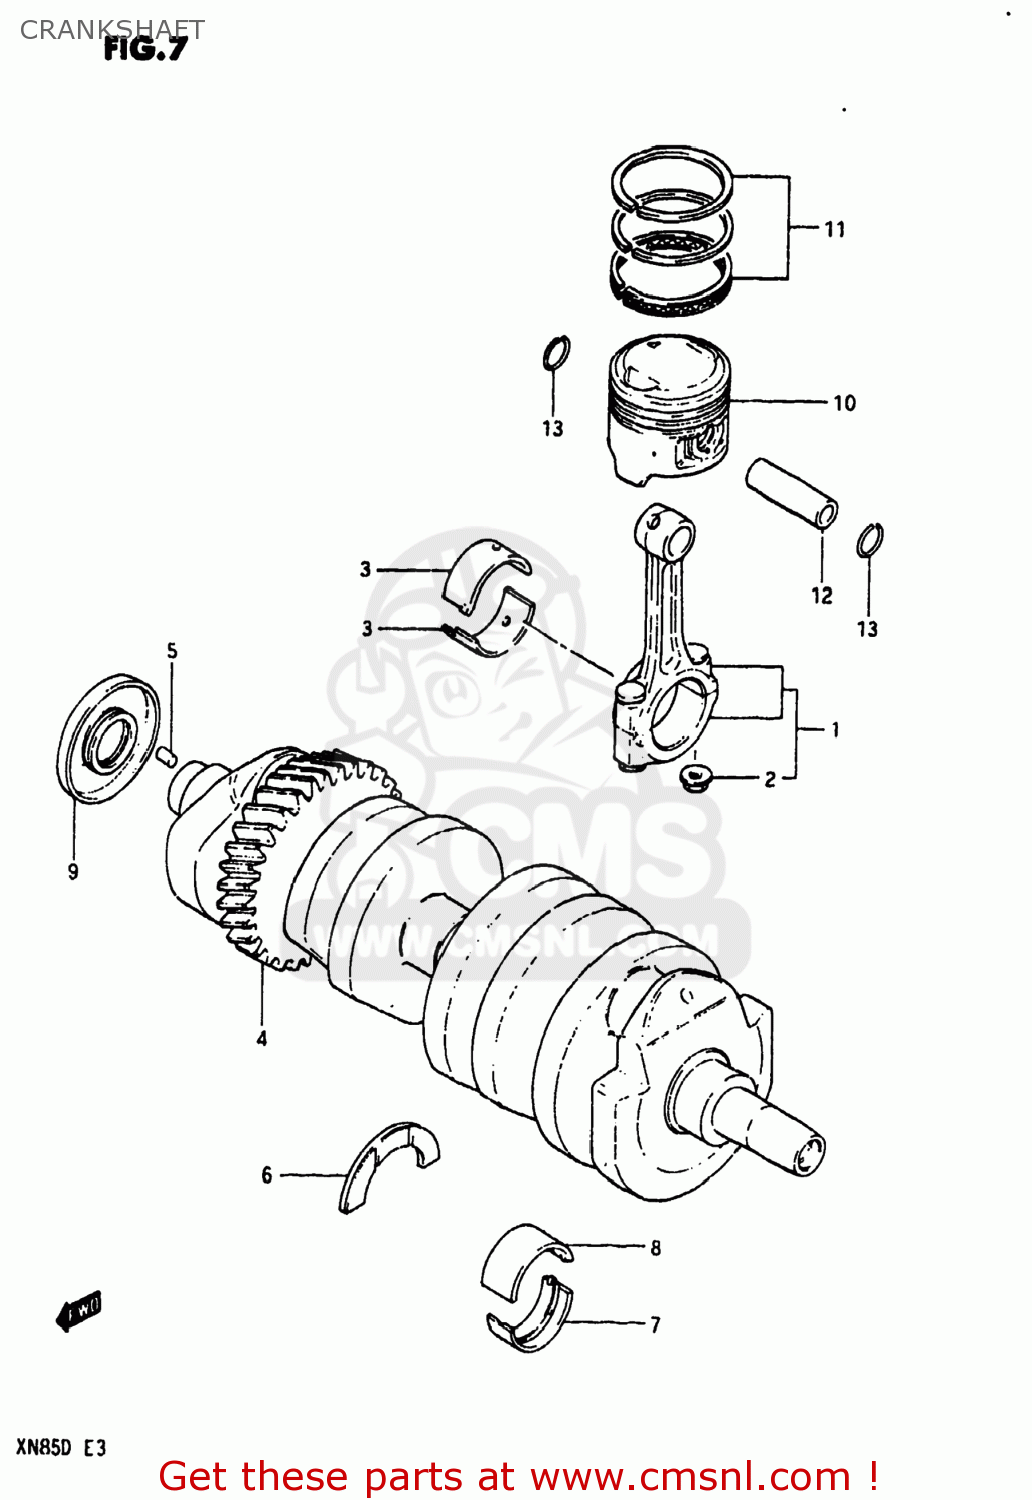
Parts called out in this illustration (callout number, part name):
1	CONNECTING ROD ASSEMBLY
2	NUT
3	BEARING,CRANK PIN
4	CRANKSHAFT
5	PIN
6	PLATE,CRANK THRUST
7	METAL CRANKSHAFT (YELLOW)
8	METAL CRANKSHAFT (BROWN)
9	OIL SEAL
10	PISTON (62.00MM)
11	RING SET,PISTON
12	PIN,PISTON
13	CIRCLIP
